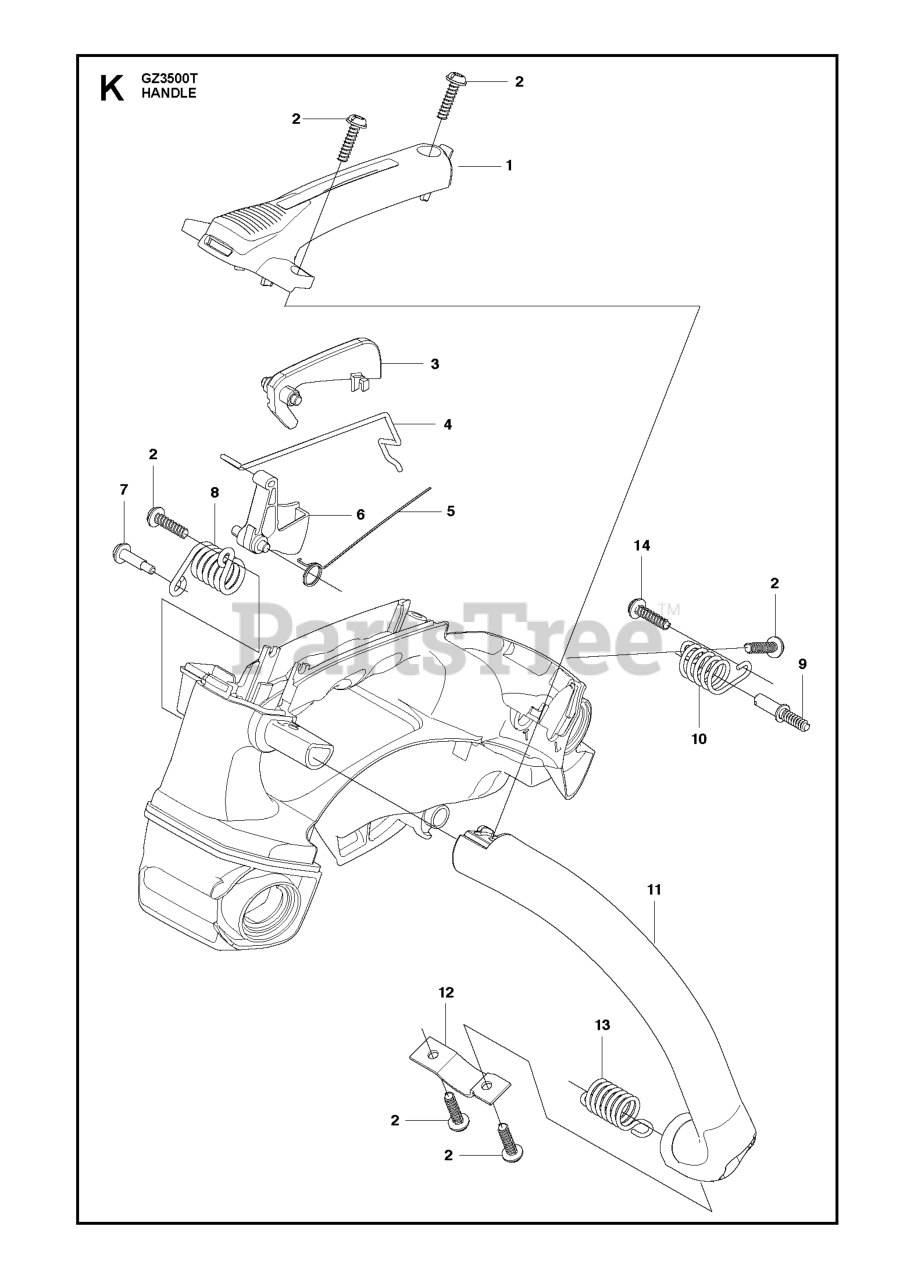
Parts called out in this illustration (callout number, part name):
1	COVER, GRIP RED
3	ARM (RPLS 335633350-335633352)
5	SPRING
6	LEVER, TH
8	SPRING, FRONT
9	BOLT
10	SPRING, PTO
11	FRONT HANDLE
13	DAMPER, MAG
14	SCREW (RPLS 267132210)
